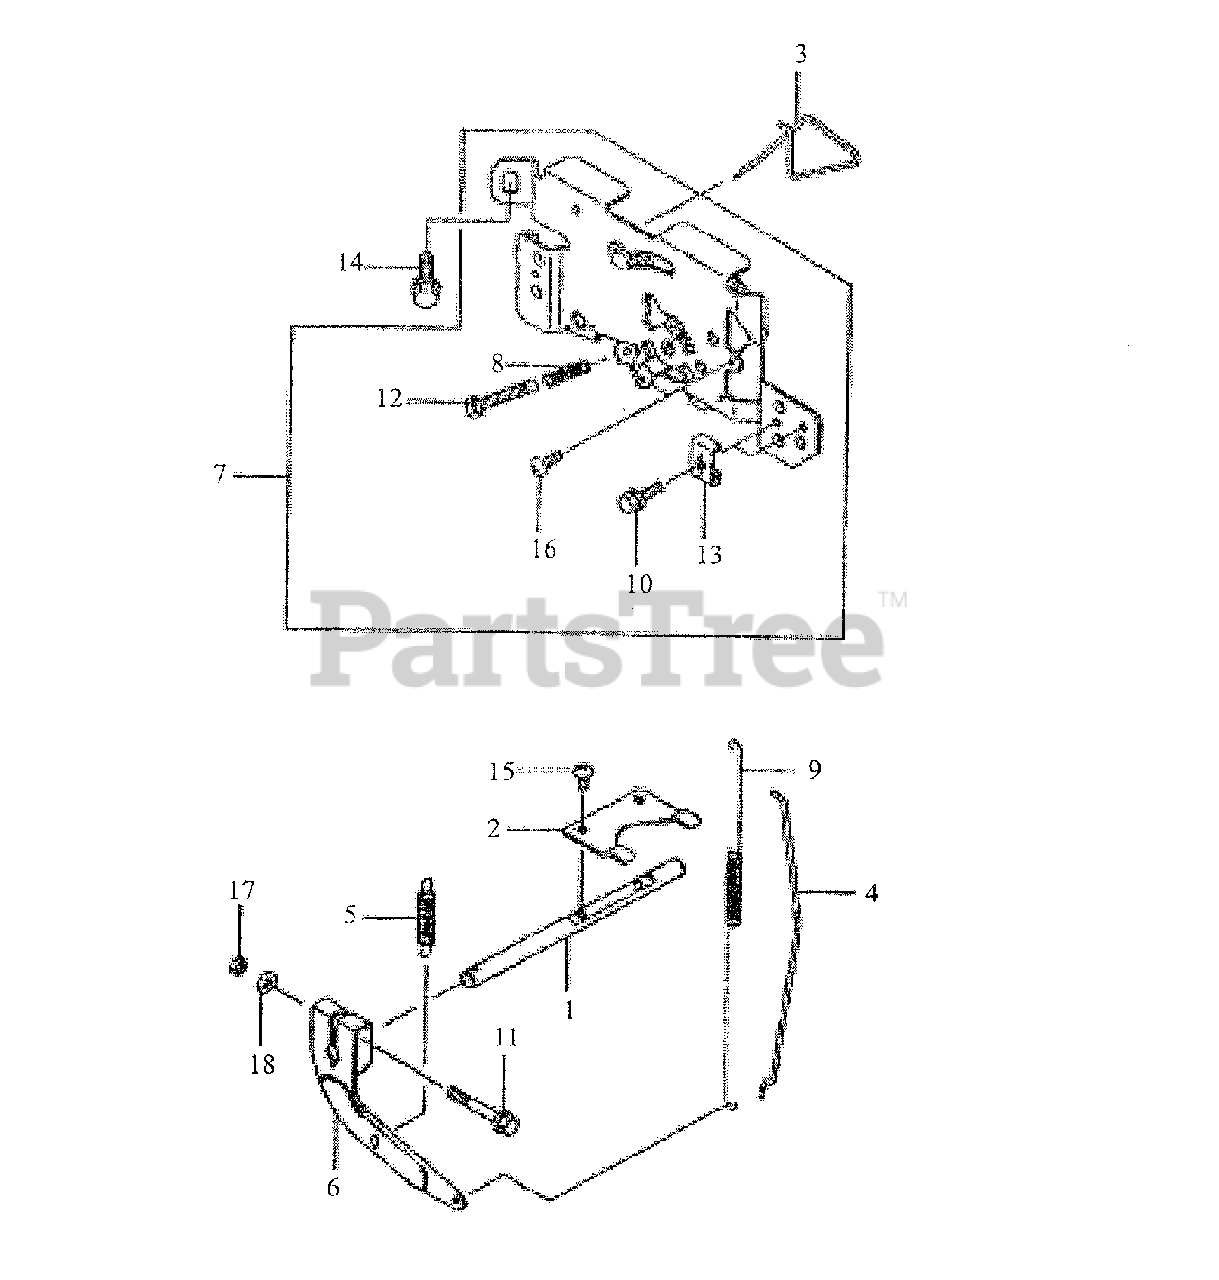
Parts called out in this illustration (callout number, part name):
2	Plate
3	Link-Choke
4	Link
5	Spring-Governor
6	Arm-Governor
7	Panel-Comp-Control
9	Spring
10	Bolt, 5 x 18 mm
11	Bolt, 6 x 30mm
12	Bolt 5 x 30 mm
14	Bolt Flange
15	Screw pan
17	Hex Nut
18	Washer-Plain
